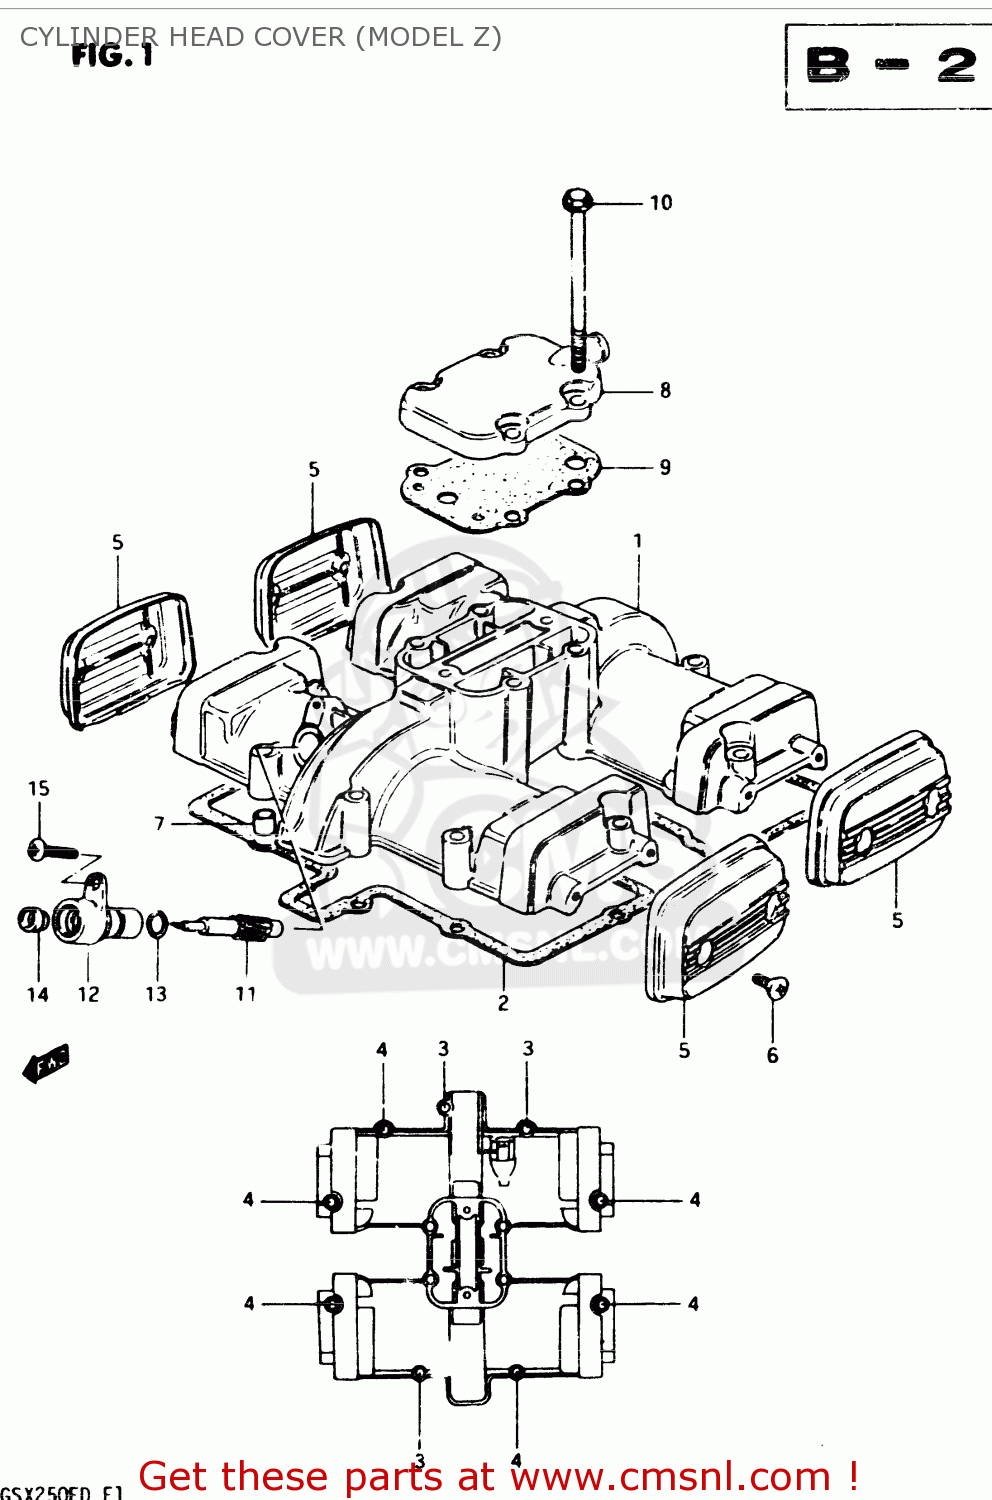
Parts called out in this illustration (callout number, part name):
1	COVER,CYLINDER HEAD
2	GASKET,CYLINDER HEAD COVER ( (MCA)
3	BOLT
4	BOLT 6X35
5	CAP,CYLINDER HEAD COVER
6	SCREW(5X12)
7	PIN(6.2X8X11)
8	COVER,BREATHER
9	GASKET,BREATHER COVER (MCA)
10	BOLT (6X75)
11	GEAR,TACHOMETER DRIVEN
12	SLEEVE,TACHOMETER DRIVE GEAR
13	SEAL,TACHOMETER DRIVEN
14	SEAL,OIL(5X12X8)
15	SCREW(5X12)
